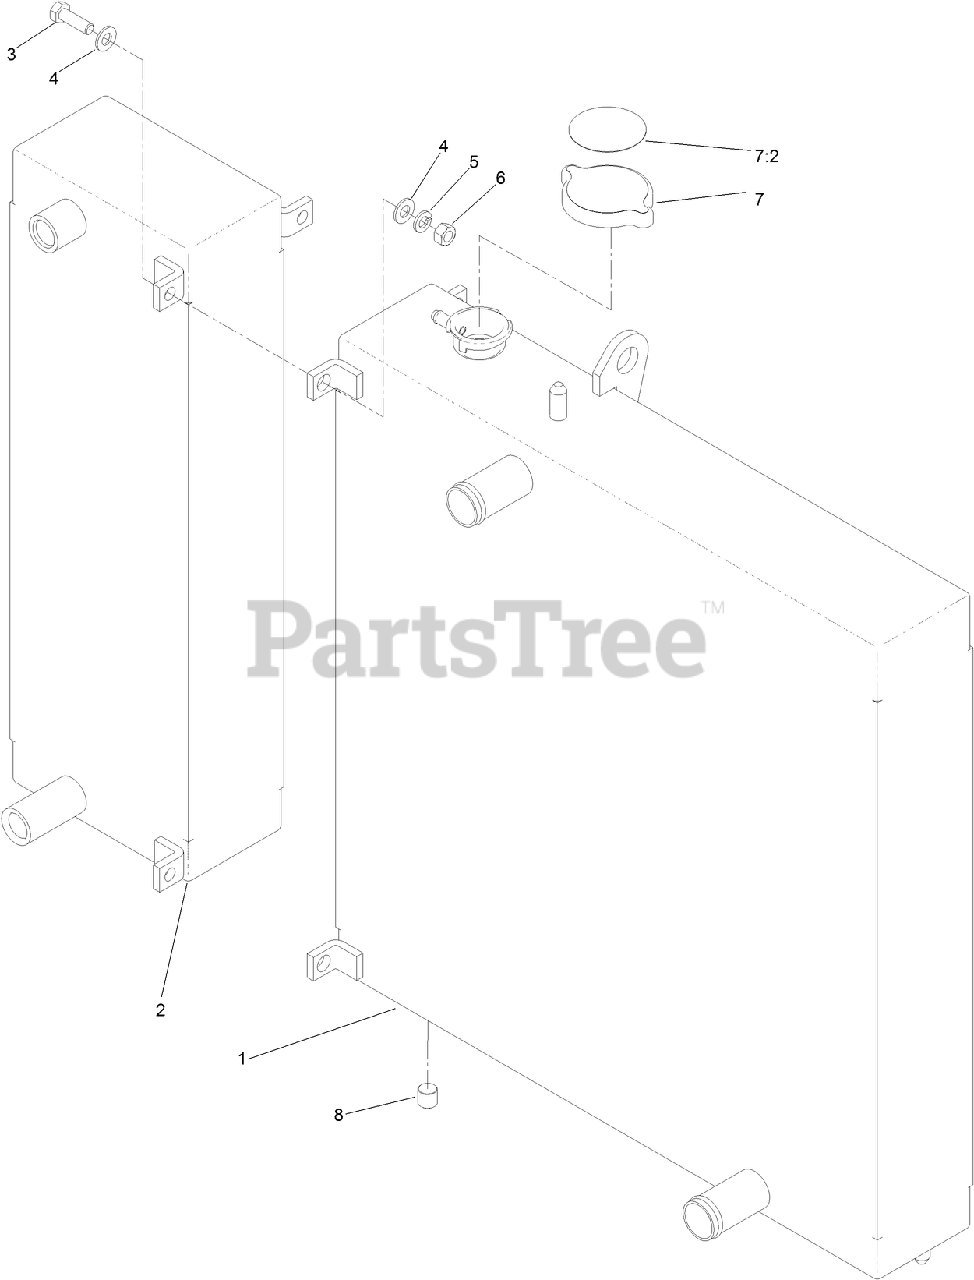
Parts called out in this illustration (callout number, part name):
1	RADIATOR
2	OIL COOLER
3	SCREW-HH
4	WASHER-PLAIN
5	WASHER-LOCK
6	NUT-HEX
7	RADIATOR CAP ASM
7:2	DECAL-DANGER
8	PLUG-PIPE
